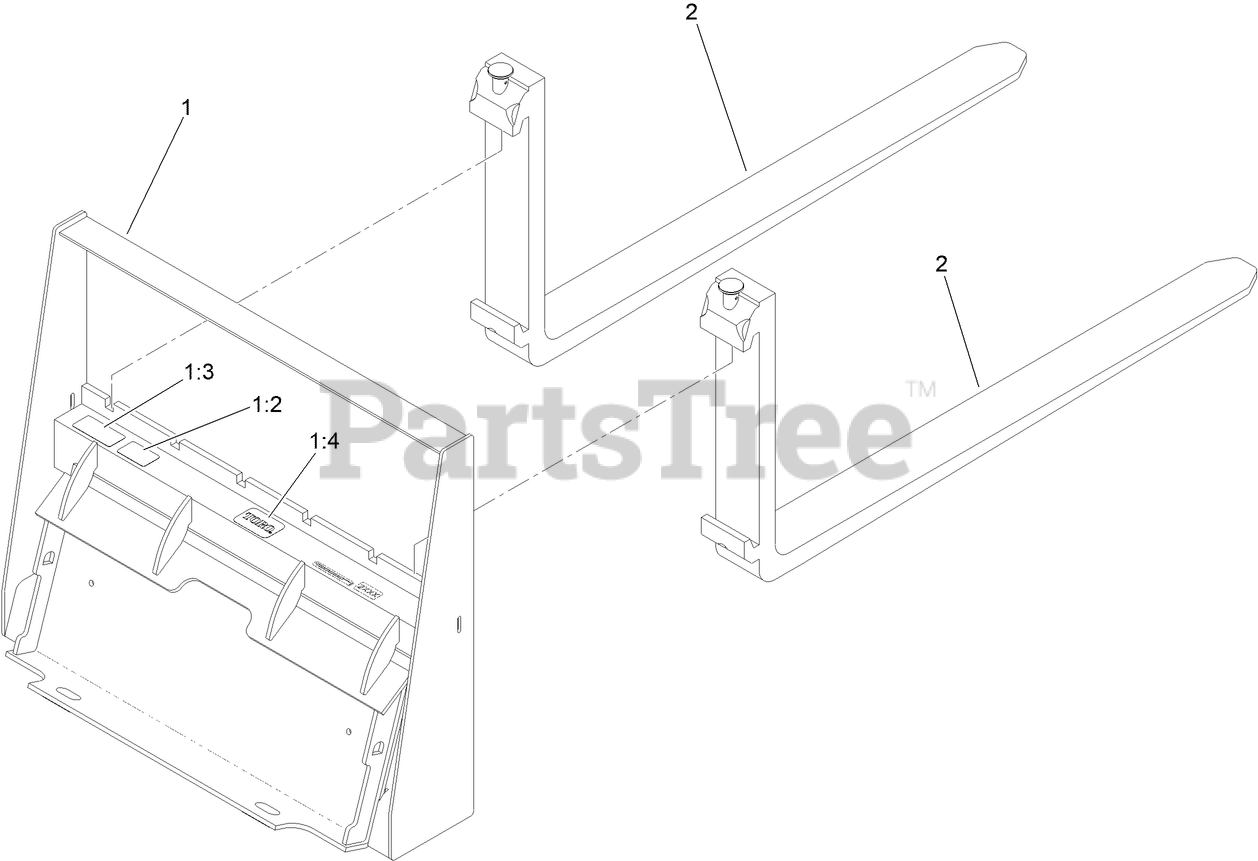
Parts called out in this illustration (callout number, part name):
1	FORK FRAME ASM,
1:2	DECAL-LOAD RATING
1:3	DECAL-WARNING, NO RIDERS
1:4	DECAL
2	TINE-FORK
